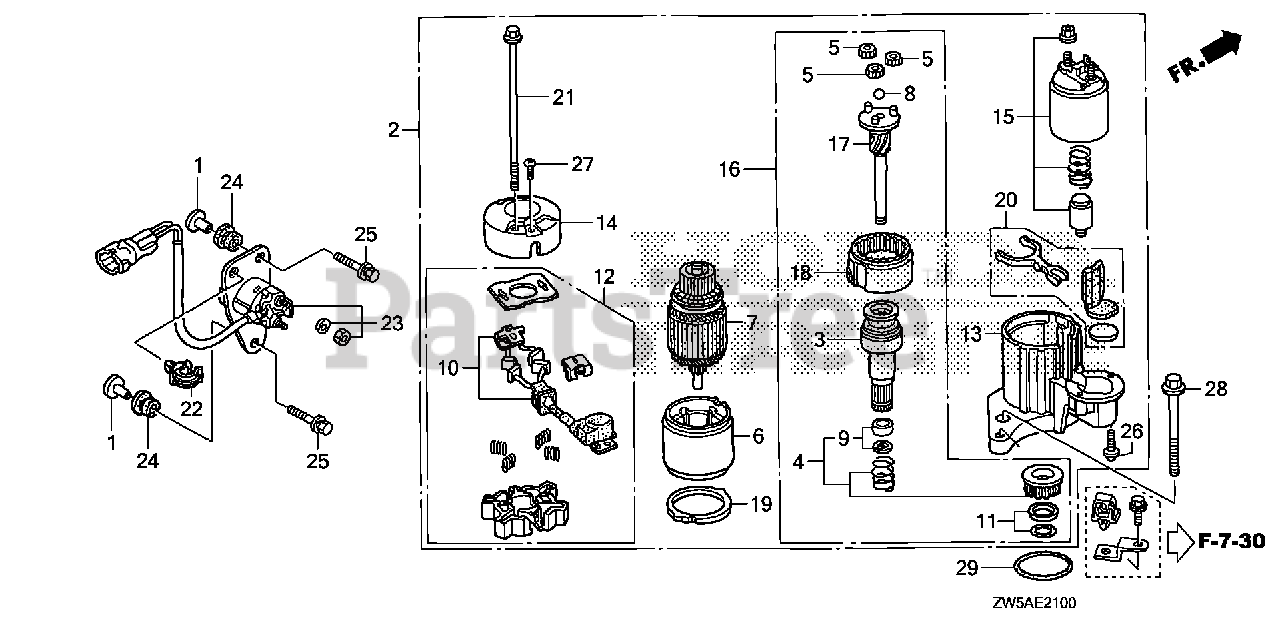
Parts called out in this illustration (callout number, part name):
1	COLLAR, FUEL TANK MOUNTING
2	STARTER MOTOR ASSY.
3	CLUTCH, OVERRUNNING
4	GEAR SET, PINION
5	GEAR ASSY., PLANETARY
8	BALL, STEEL
9	STOPPER SET, PINION
11	STOPPER SET, SLEEVE
12	HOLDER, BRUSH
13	BRACKET, FR.
14	BRACKET, RR.
15	SWITCH ASSY., MAGNET
16	SHAFT ASSY., CLUTCH
17	SHAFT ASSY., GEAR
18	GEAR ASSY. (INNER)
21	BOLT A, THROUGH
22	CLAMP, WIRE
23	SWITCH ASSY., STARTER MAGNETIC
24	RUBBER A, NUMBER BRACKET CUSHION
25	BOLT-WASHER (6X27) (CT200)
26	SCREW, PAN (6X22) (SPECIAL)
27	SCREW, PAN (5X8)
28	BOLT, FLANGE (10X35)
29	O-RING (54.4X3.1)
